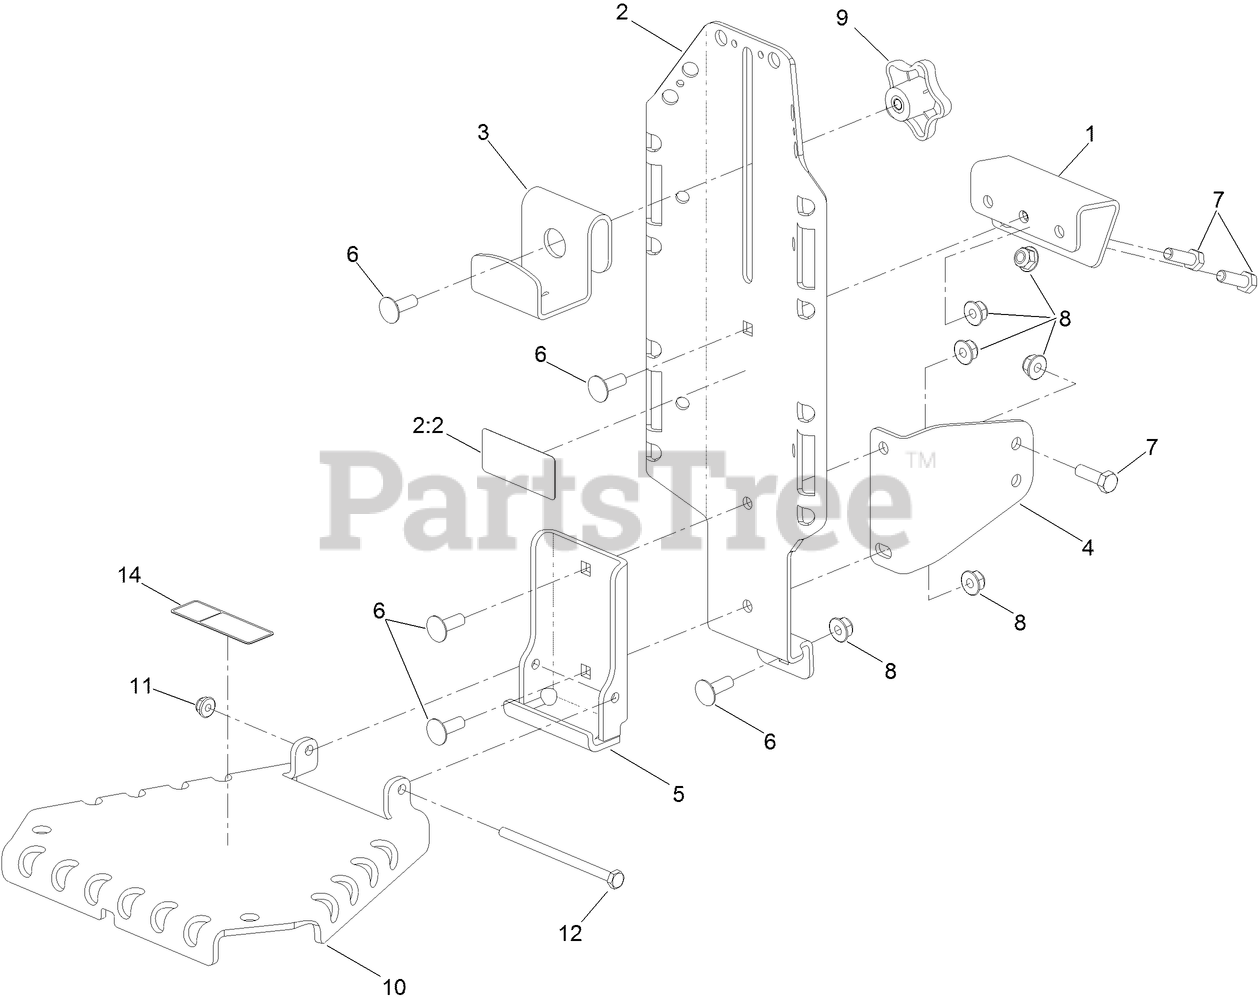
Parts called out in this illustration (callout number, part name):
1	MOUNT-BUCKET, UPPER
2	MOUNT BRACKET ASM
2:2	DECAL-WEIGHT, MAXIMUM
3	BRACKET-TOP
4	BRACKET-SUPPORT, LOWER
5	BRACKET-SUPPORT, HINGE
6	BOLT-CARR
7	SCREW-HH
8	NUT-HF, NI
9	KNOB-HANDLE
10	BRACKET-SUPPORT, HINGED
11	NUT-HF
12	SCREW-HH
14	DECAL-NO STEP/RIDERS
